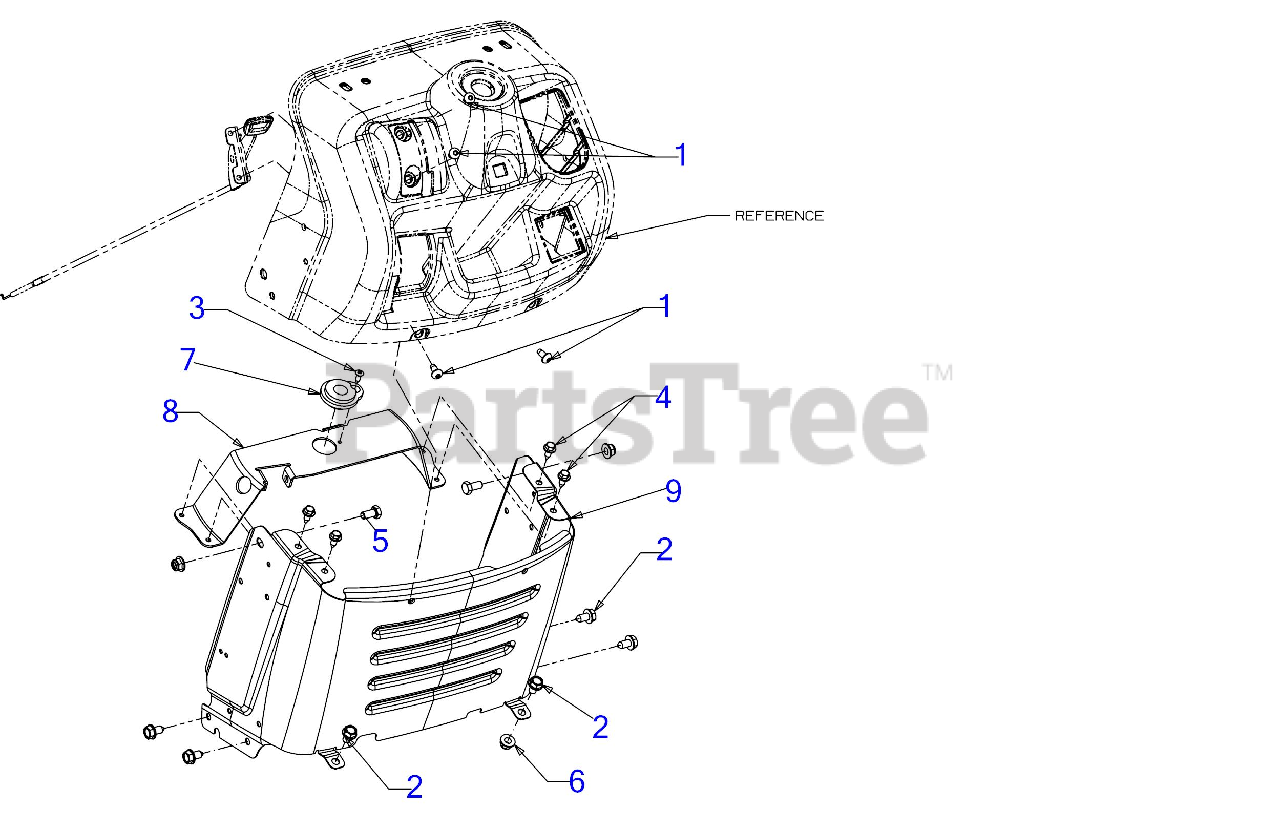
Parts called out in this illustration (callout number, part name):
1	SCREW 1/4-20 x .5
2	SCREW 5/16-18 x .625
3	SCREW #10-16 x .625
4	SCREW 1/4-20X.625
5	SCREW 5/16-18X .625 GR5
6	FLANGE LOCK NUT 5/16-18
7	BEARING
